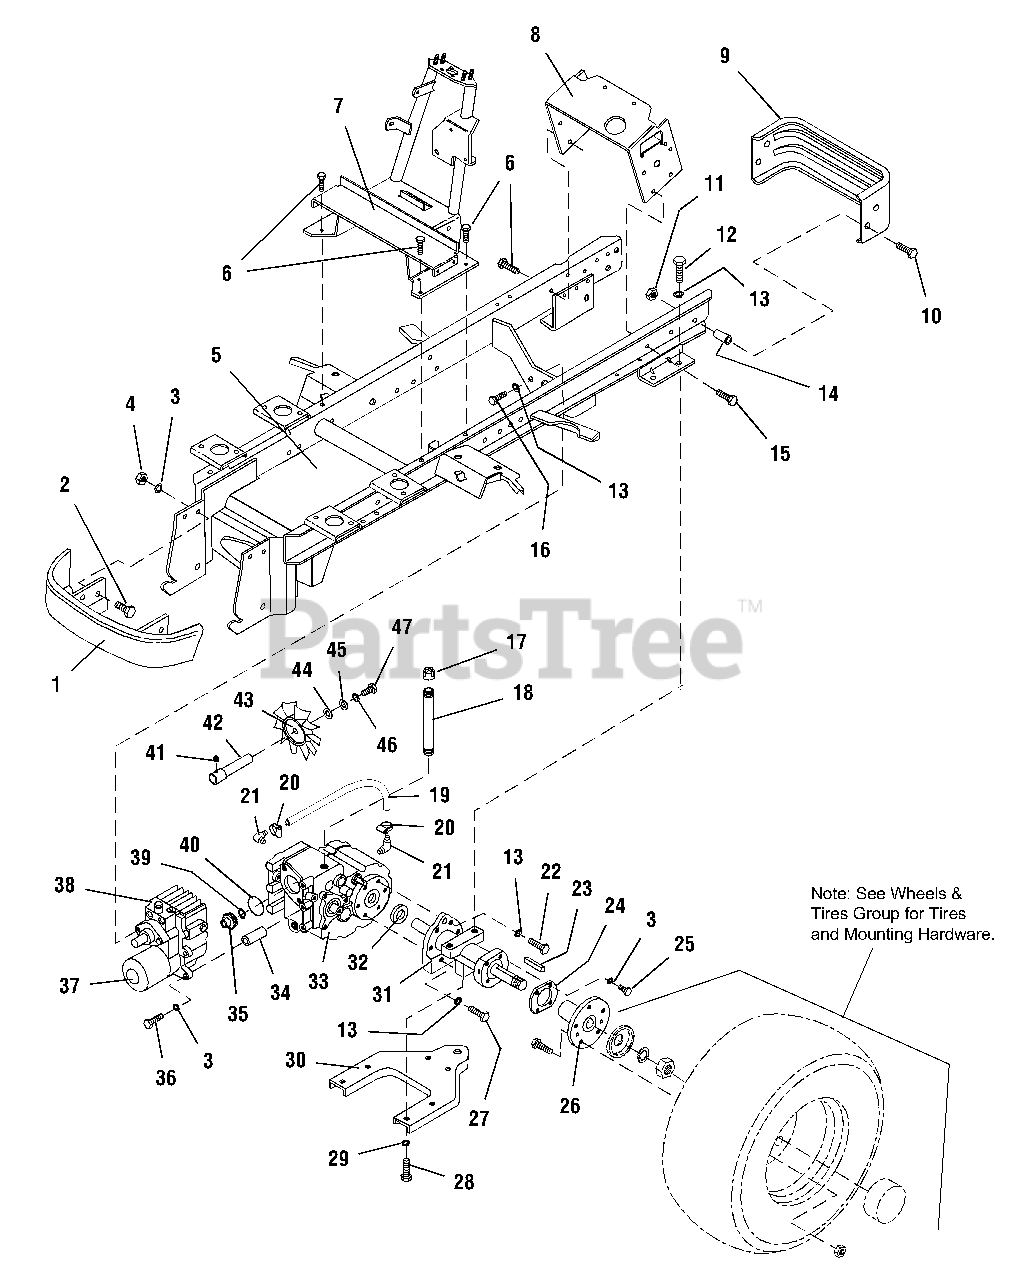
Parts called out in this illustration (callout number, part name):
1	FRONT BUMPER ASSEMBLY
2	CAPSCREW, Hex Hd, 3/8-16 x 1-1/4
3	LOCKWASHER, 3/8
4	NUT, Hex, Full, 3/8-16
6	CAPSCREW, Hex Hd, Taptite, 5/16-18 x 3/4
7	TOWER ASSY, Steering
8	SUPPORT, Seat Deck
9	REAR BUMPER ASSEMBLY
10	CARRIAGE BOLT, (Short Neck) 5/16-18 x 2
11	NUT, Hex, Whizlock, 5/16-18
12	CAPSCREW, Hex Hd, 1/2-13 x 1-1/2
13	LOCKWASHER, 1/2
14	SPACER, RR Bumper
15	CAPSCREW, Hex Hd, Taptite, 5/16-18 x 5/8
16	CAPSCREW, Hex Hd, 1/2-13 x 1-1/4
17	CAP, Oil Fill
18	TUBE, Oil Fill
19	HOSE, Fluid Level
20	CLAMP, SAE #6
21	FITTING, Elbow
22	CAPSCREW, Hex Hd, 1/2-13 x 1-1/2
23	KEY, 5/16 x 5/16 x 2-1/2
24	PLATE, Bearing Retainer
25	CAPSCREW, Hex Hd, 3/8-16 x 5/8
26	HUB ASSEMBLY, Rear
27	CAPSCREW, Hex Hd, 1/2-13 x 2
28	CAPSCREW, Hex Hd, 5/8-11 x 1-1/4
29	LOCKWASHER, 5/16
31	HOUSING ASSEMBLY, Axle
32	SPACER, Axle
33	TRANSAXLE, 2 Speed
34	SPACER, Mounting
35	GEAR, Bevel
36	CAPSCREW, Hex Hd, 3/8-16 x 4
37	FILTER, Oil
38	HYDROSTATIC PUMP
39	RING, Retaining #62
41	SET SCREW, 1/4-20 x 5/16
42	SHAFT & HUB, Fan
44	WASHER, Plain, 1/4
45	LOCKWASHER, Dished, 1/4
46	LOCKWASHER, 1/4
47	CAPSCREW, Hex Hd, 1/4-20 x 3/4
